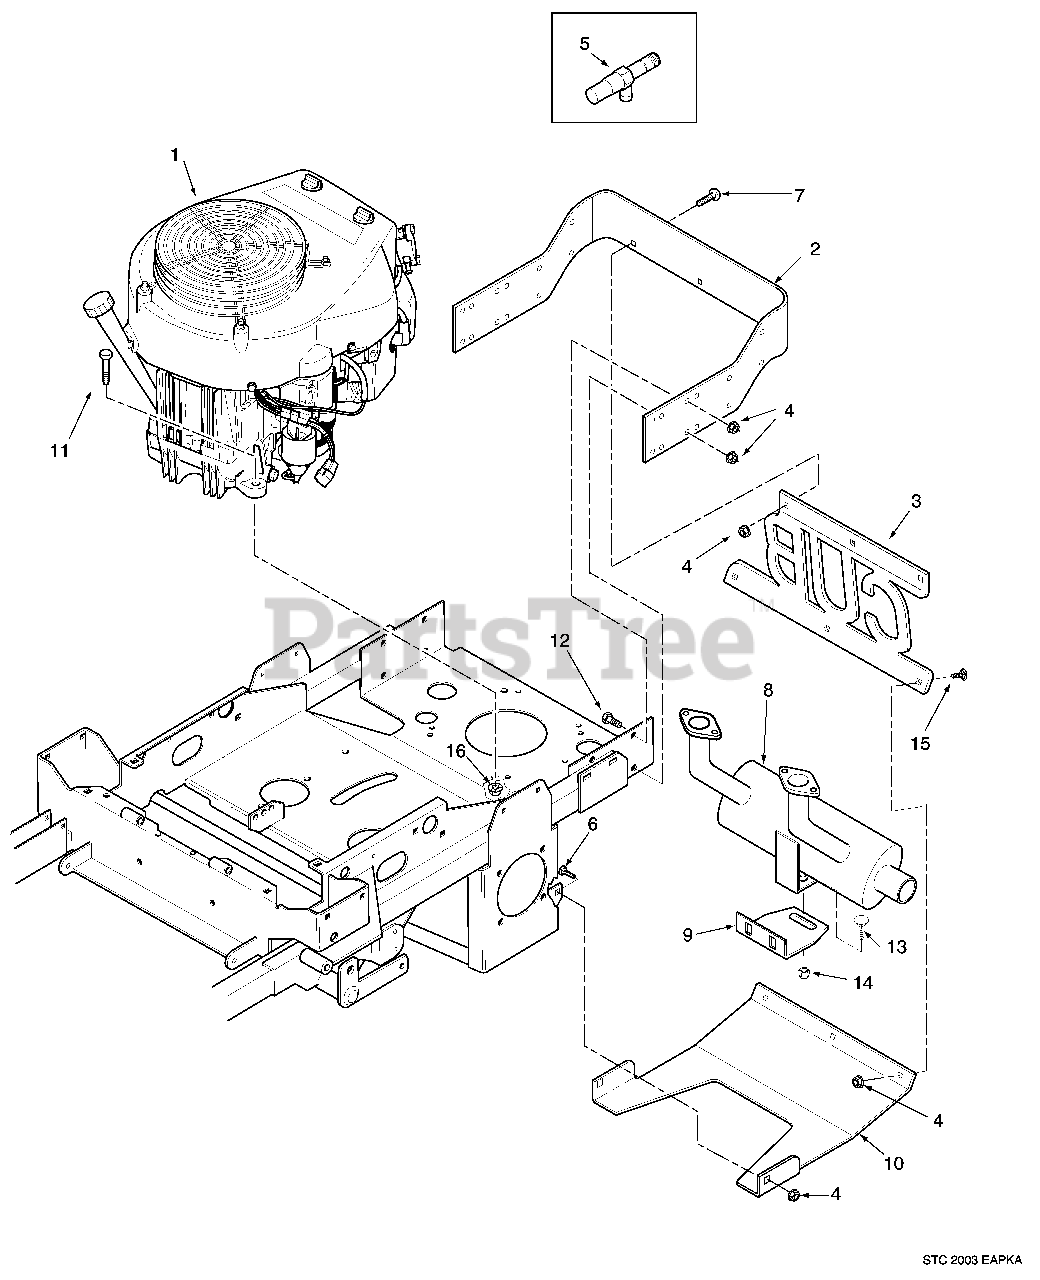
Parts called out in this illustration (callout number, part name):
1	Engine, Kawasaki (FH601V-AS29)
2	Bumper, Rear
3	Shield, Rear
4	Nut, Serr. Flange 3/8-16
5	Extension, Oil Drain 4"
6	Bolt, Carr. 3/8-16 x 1"
7	NOT USED ON THIS MODEL
8	Muffler
9	Bracket, Muffler
10	Plate, Skid
11	Bolt, Hex Head 5/16-18 x 1-1/2"
12	Bolt, Hex Head 3/8-16 x 1"
13	Bolt, Hex Head 5/16-18 x 3/4"
14	Nut, Serr. Flange 5/16-18
15	Bolt, Carr. 3/8-16 x 3/4"
16	Nut, Serr. Flange 5/16-18
